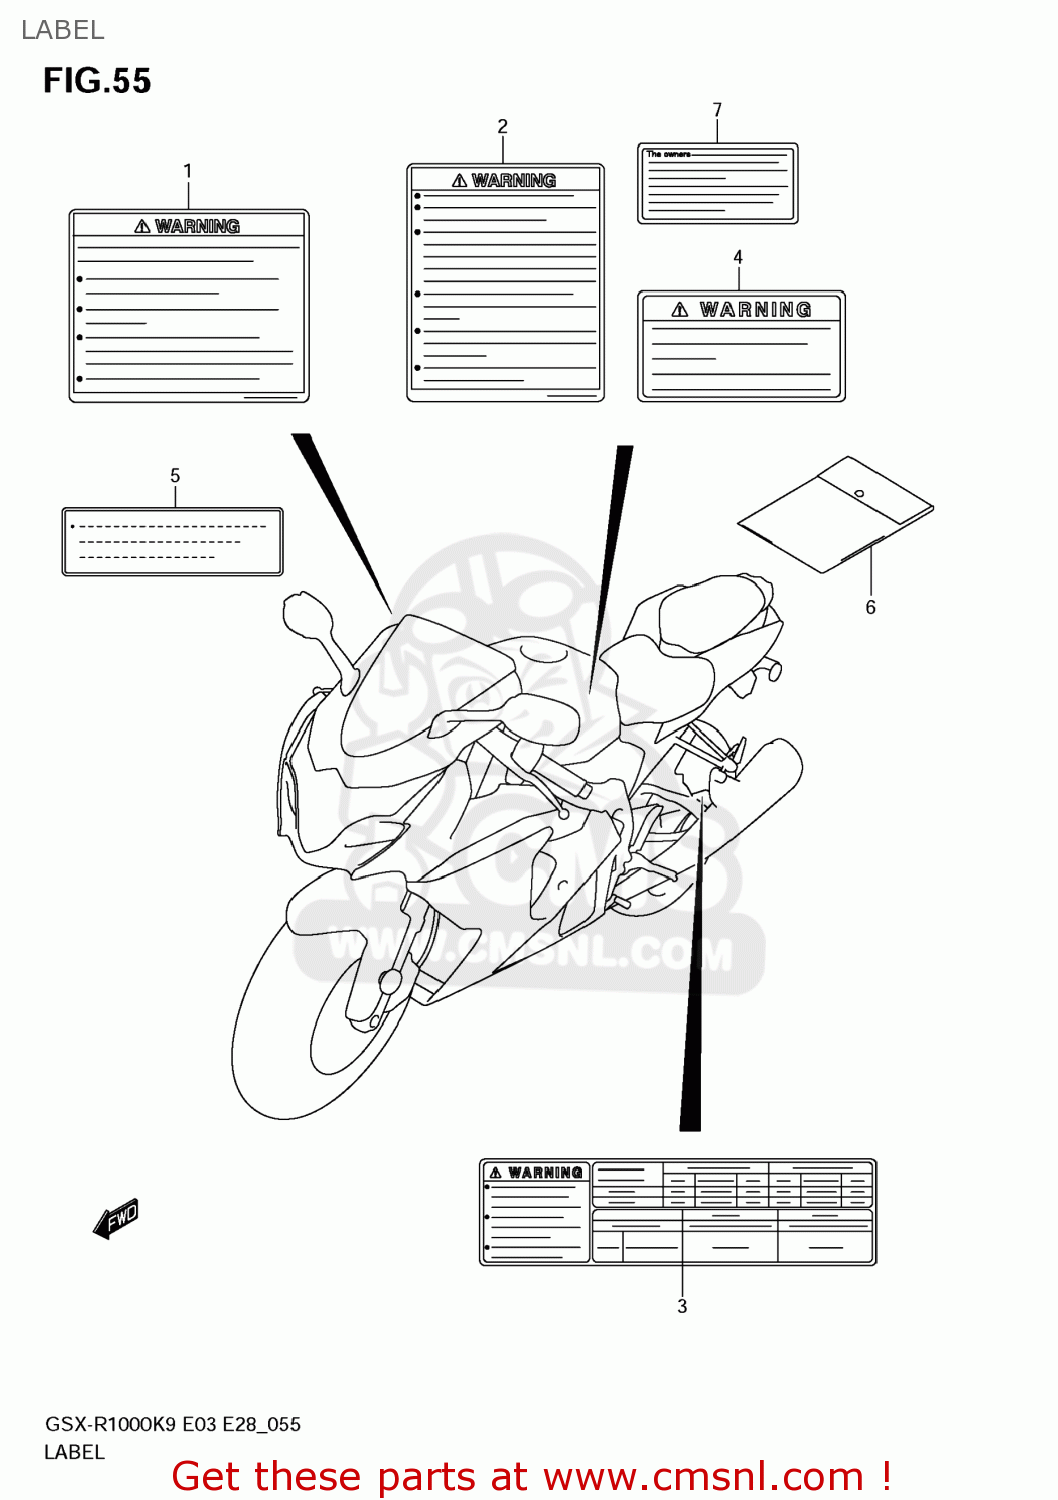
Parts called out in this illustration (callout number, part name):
1	LABEL,GENERAL WARNING
2	LABEL,SCREEN
3	LABEL,TIRE INFORMATION
4	LABEL,WARNING STEERING
5	LABEL,FUEL INFORMATION
6	BAG COMP,OWNERS MANUAL
7	LABEL,MANUAL NOTICE
8	MANUAL,OWNER'S
